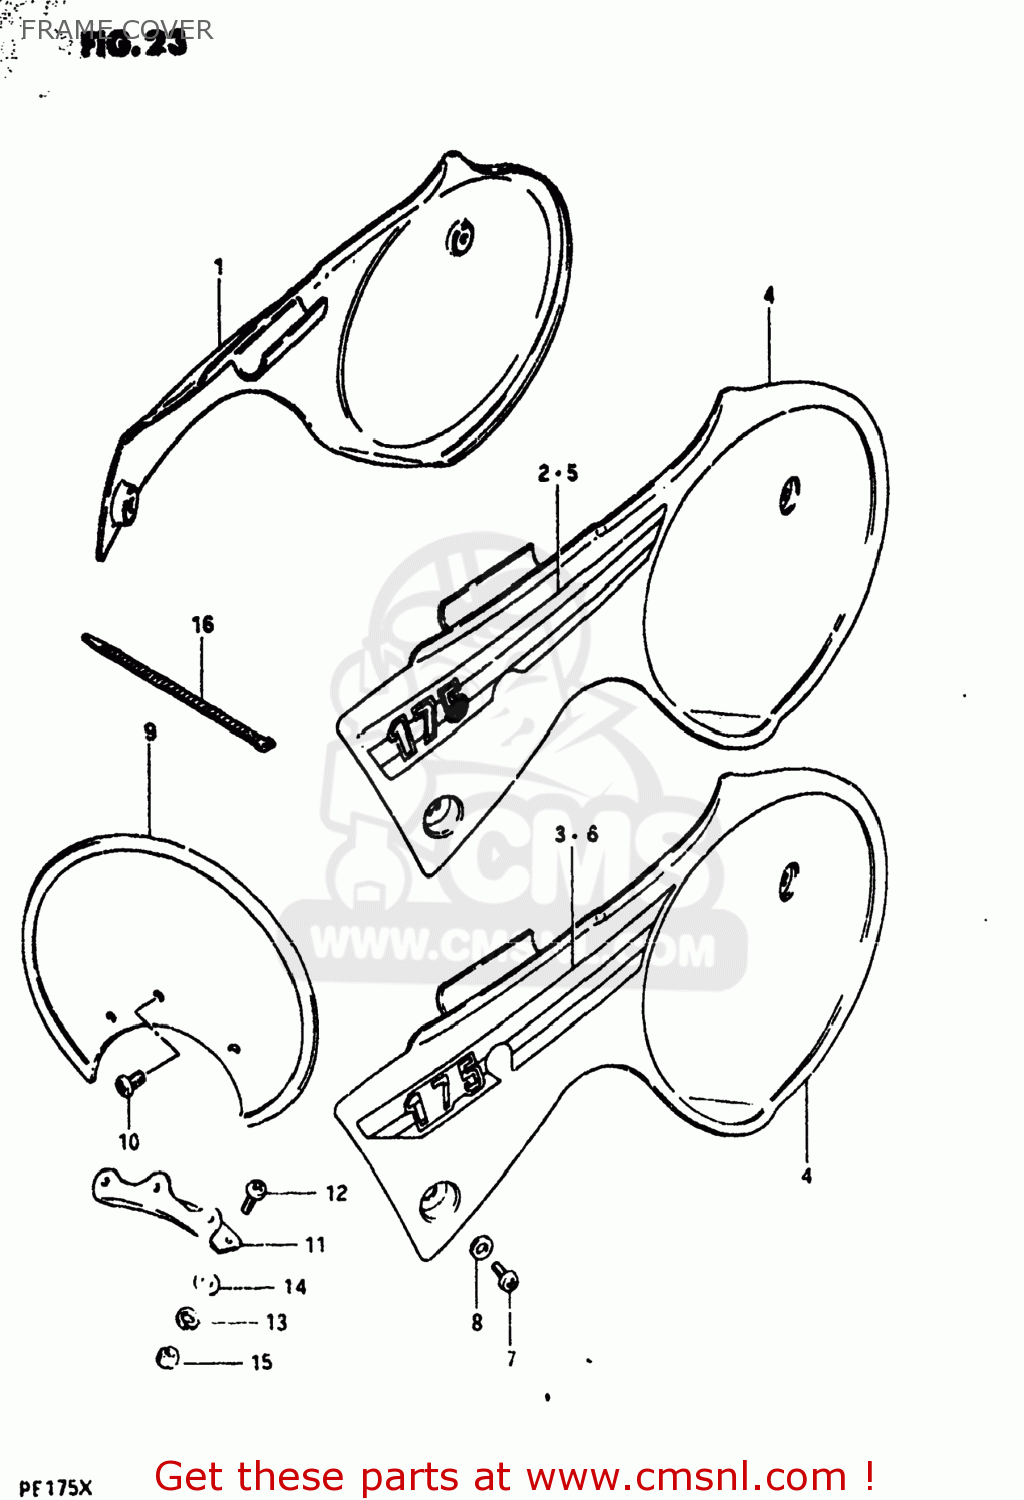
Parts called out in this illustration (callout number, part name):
1	COVER,FRAME,R(YELLOW)
2	TAPE,FRAME COVER
3	TAPE,FRAME COVER
4	COVER,FRAME,L(YELLOW)
5	TAPE,FRAME COVER
6	TAPE,FRAME COVER,LEFT
7	SCREW
8	WASHER
9	PLATE,NUMBER,FRONT
10	SCREW
11	BRACKET
12	SCREW
13	LOCK WASHER
14	WASHER
15	NUT
16	CLAMP
